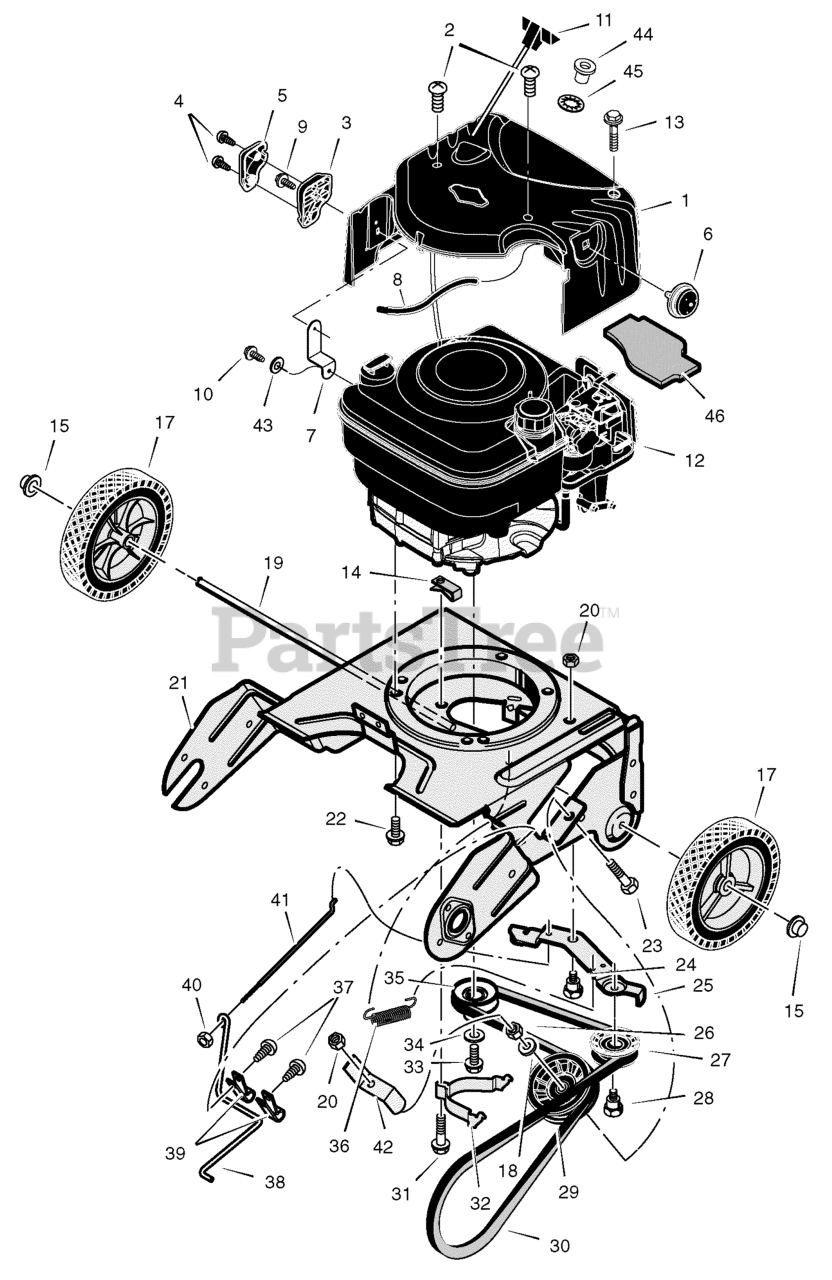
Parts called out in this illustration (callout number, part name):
1	Cover, Top
3	Base, Chute Rod
5	Cover, Chute Rod
6	Primerbulb, Red
7	Bracket, Engine Chute
11	Handle, Starter
12	Engine
14	Retainer
15	Nut, Push Cap
17	Wheel & Tire
18	Washer
21	Frame, Motor Box
22	Bolt
24	Bolt, Shoulder
25	Bracket,
26	Idler Arm Nut
27	Pulley, V-Belt
28	Bolt, Shoulder
29	Pulley, Flat Idler
32	Guide, Belt
33	Screw
34	Washer
35	Pulley
37	Screw
38	Arm, Brake
40	Nut
41	Rod, Adjustment
42	Guide, Belt
43	Lockwasher
44	Guide, Rope
45	Spring Grip Washer
46	Seal, Foam
